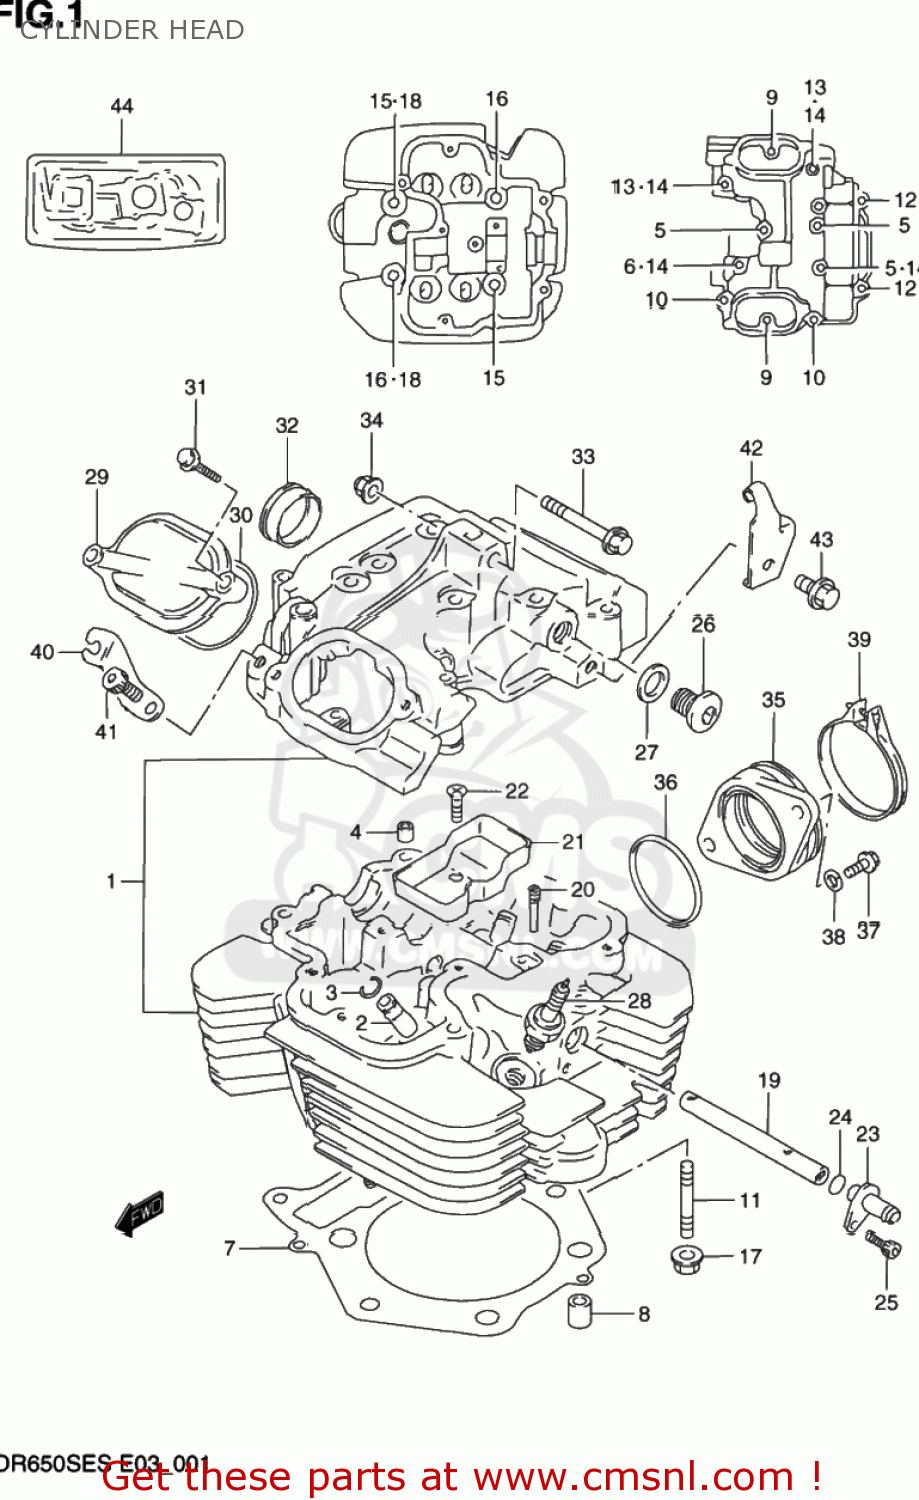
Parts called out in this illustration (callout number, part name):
1	HEAD ASSEMBLY,CYLINDER
2	GUIDE,VALVE
3	RING,SNAP
4	PIN(6.2X8X11)
5	BOLT
6	BOLT 6X55
7	GASKET,CYLINDER HEAD (NAS)
8	PIN
9	BOLT
10	BOLT
11	STUD
12	BOLT
13	BOLT
14	GASKET (NAS)
15	BOLT(10X190)
16	BOLT(10X215)
17	NUT
18	GASKET(10.5X22X2) (NAS)
19	PIPE,CYLINDER HEAD OIL
20	SCREW (L:19.5)
21	PLATE,CYLINDER HEAD CHAMBER
22	SCREW
23	UNION,CYLINDER HEAD OIL
24	O RING,HEAD GASKET
25	BOLT
26	PLUG
27	GASKET(13.8X18.8X4.8) (NAS)
28	SPARK PLUG DP9EA-9
29	CAP,INSPECTION
30	O RING(D:2.4,ID:23)
31	BOLT
32	PLUG(OD:30)
33	BOLT 8X53
34	NUT
35	PIPE,INTAKE
36	O RING(D:2.4,ID:45.7)
37	BOLT
38	WASHER
39	CLAMP
40	LEVER,DECOMP SHAFT RH
41	BOLT
42	HOLDER,DECOMP CABLE
43	BOLT 8X16
44	GASKET SET (NAS)
